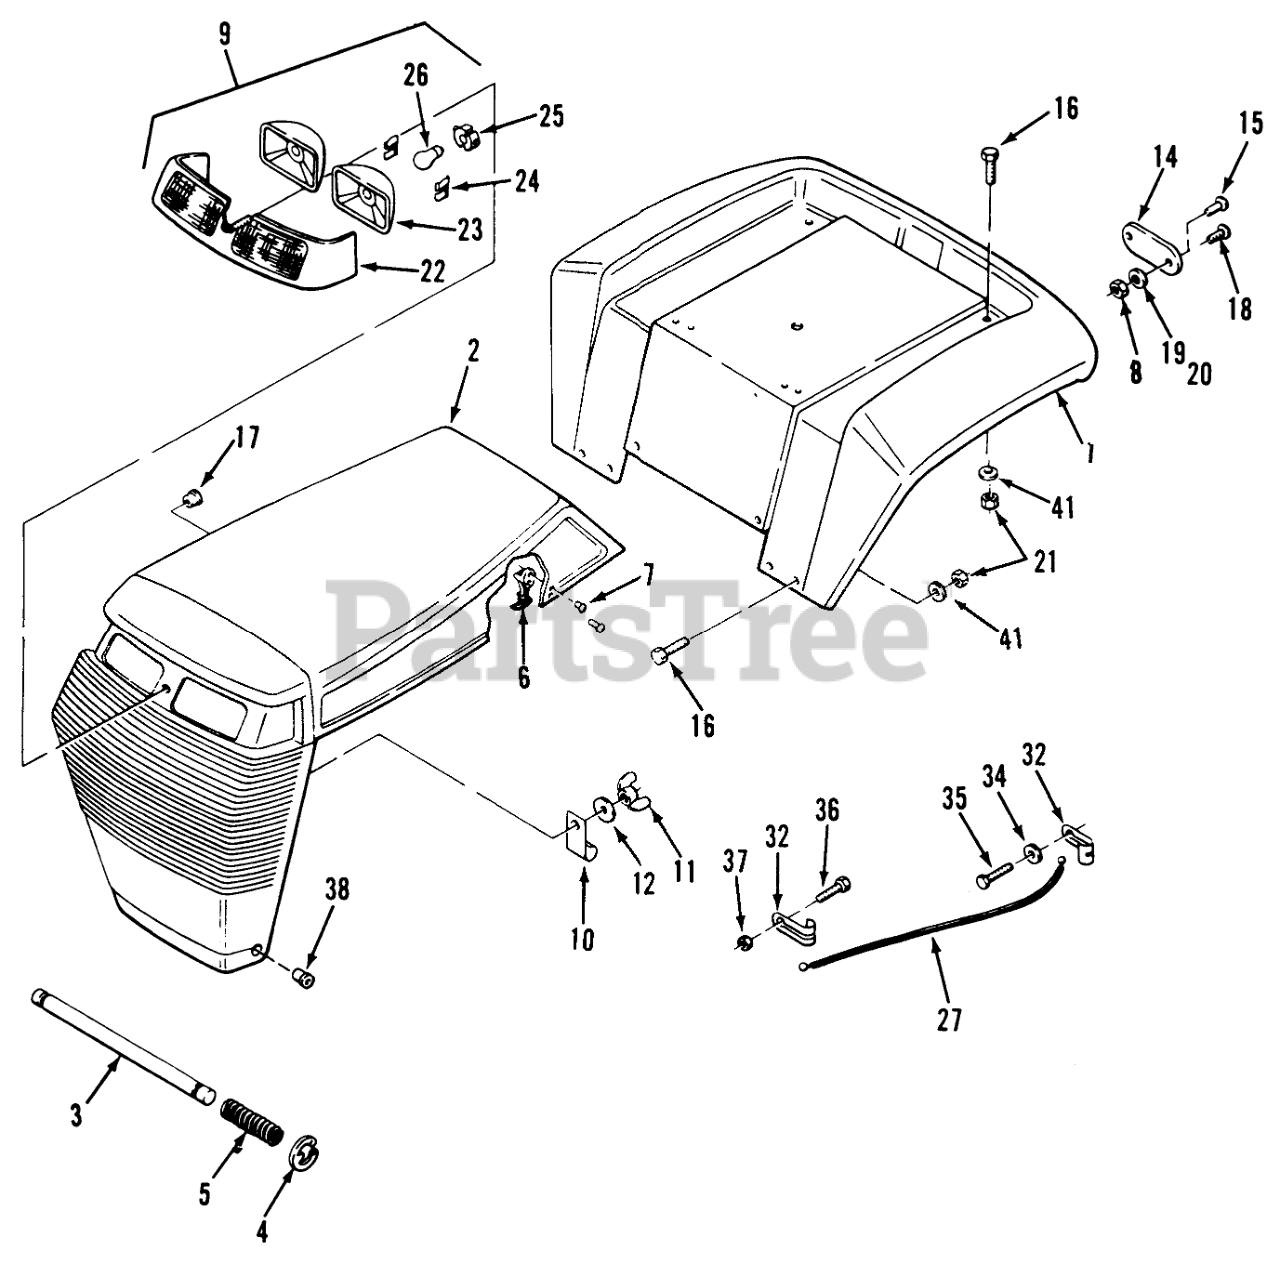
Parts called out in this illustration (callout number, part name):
1	FENDER R
2	Hood & Grill
4	E-Ring
5	SPRING
6	HANDLE ASM
7	RIVET-POP
9	Headlight Bar Assembly (Incl. Ref. #22-24 & 26) (212-5 & 212-H)
10	J-CLIP
11	WING NUT
12	WASHER
14	Reflector
15	Poprivet
16	SCREW-CARR
17	BUSHING-NYLON 1.093
18	Screw
19	WASHER
20	Lockwasher
21	Nut
22	LIGHT-BAR BLACK
23	LIGHT POD
24	RETAINER
25	SOCKET-HEADLIGHT
26	BULB
27	CABLE-ASS'Y
32	CLEVIS
34	Washer
35	Bolt
36	Screw-Machine
37	Nut
38	NYLINER BUSHING
41	Washer-Lock
